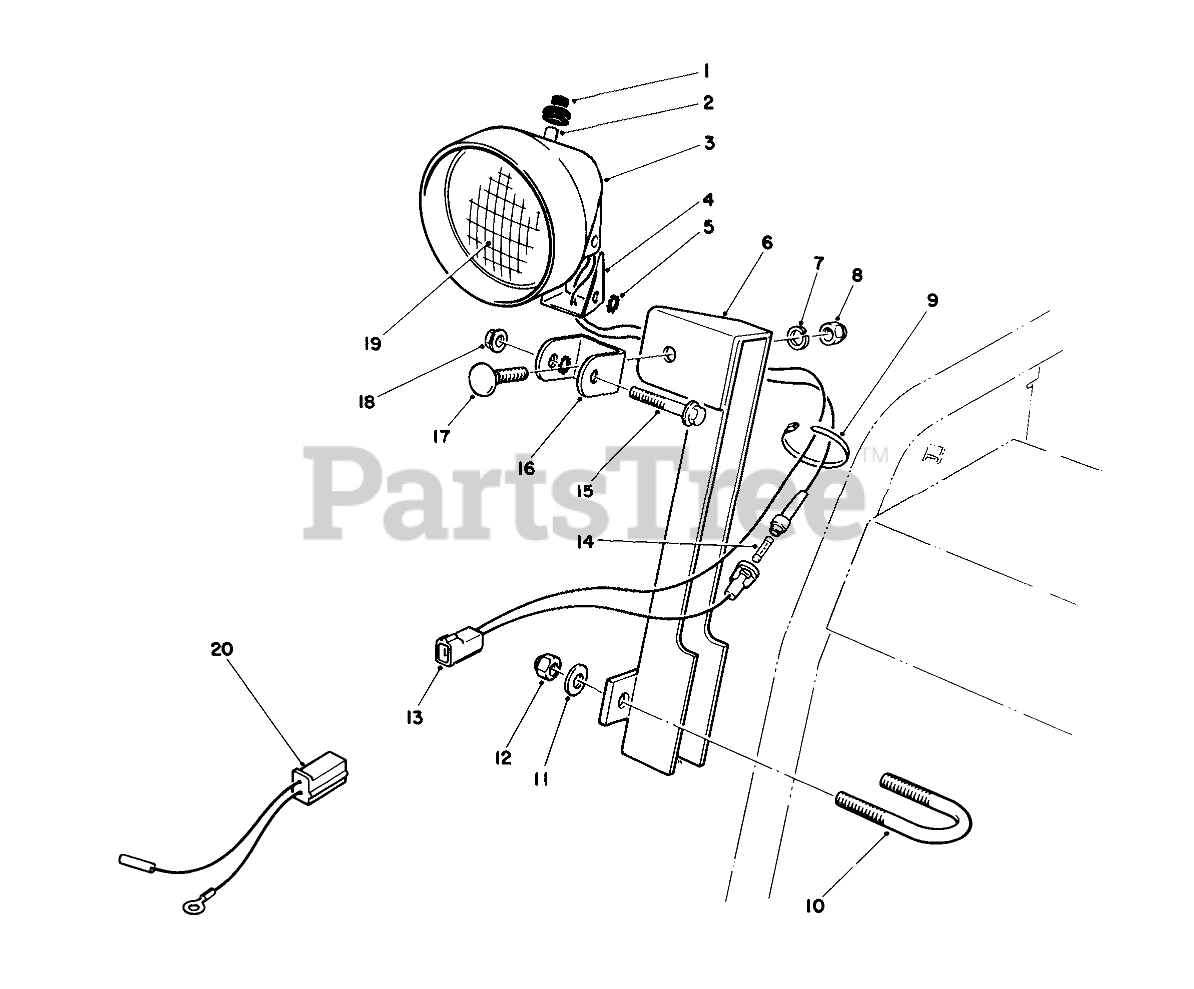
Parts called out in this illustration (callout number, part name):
1	BOOT-SWITCH
2	SWITCH ASM
3	Bucket-Headlamp
4	TO BE DISCONTINED-NOT NEEDED ON PRODUCT
5	WASHER-LOCK
6	Mount-Lamp
7	WASHER-LOCK
8	NUT-HEX
9	TIE-CABLE
10	U-BOLT
11	WASHER-PLAIN
12	NUT-LOCK, NI
13	WIRE ASM
14	Fuse-7-1/2 Amp.
15	SCREW-HH
16	BRACKET
17	BOLT-CARR
18	NUT-HF
19	SEALED BEAM
20	WIRE ASM
